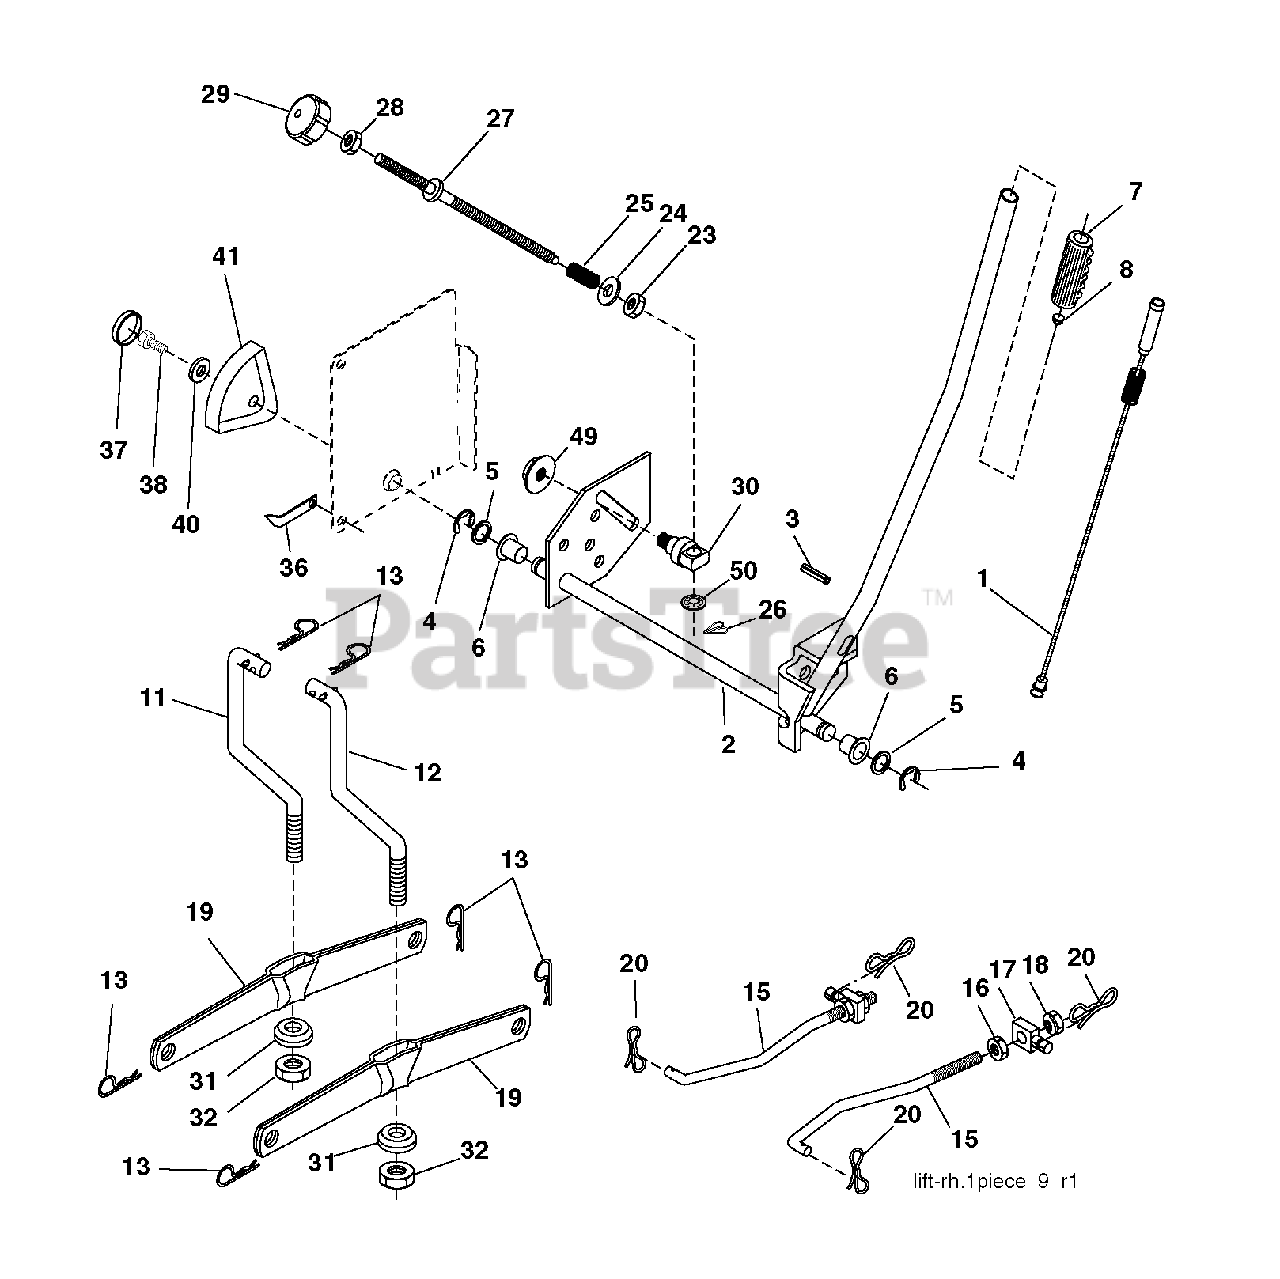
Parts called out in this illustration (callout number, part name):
1	PLUNGER.ASM.LIFT.LVR.BLK.17.32
2	SHAFT ASM R HANDLE
3	PIN GROOVE
4	RETAINING RING LT
6	BEARING.NYLON
7	GRIP HANDLE
8	PLUNGER BUT KIT
11	LINK
12	LINK
13	RETAINER-SPRNG RB
15	LINK.SUSPENSION.FRONT
16	NUT
18	NUT
19	ARM.REAR.SUSPENSION
20	PIN.COTTER.7/16.BOW TI
25	SPRING**
26	RETAINER CLIP
27	ROD ADJ LIFT
28	NUT
29	KNOB INF 3/8-16
31	BEARING.PIVOT.LIFT
32	NUT CROWNLOCK 3/8-24
36	POINTER, HEIGHT INDICATOR
37	PLUG,HOLE
38	SCREW 5/16-18X1
41	HEIGHT INDICATOR
49	NUT
50	NUT PUSH M
